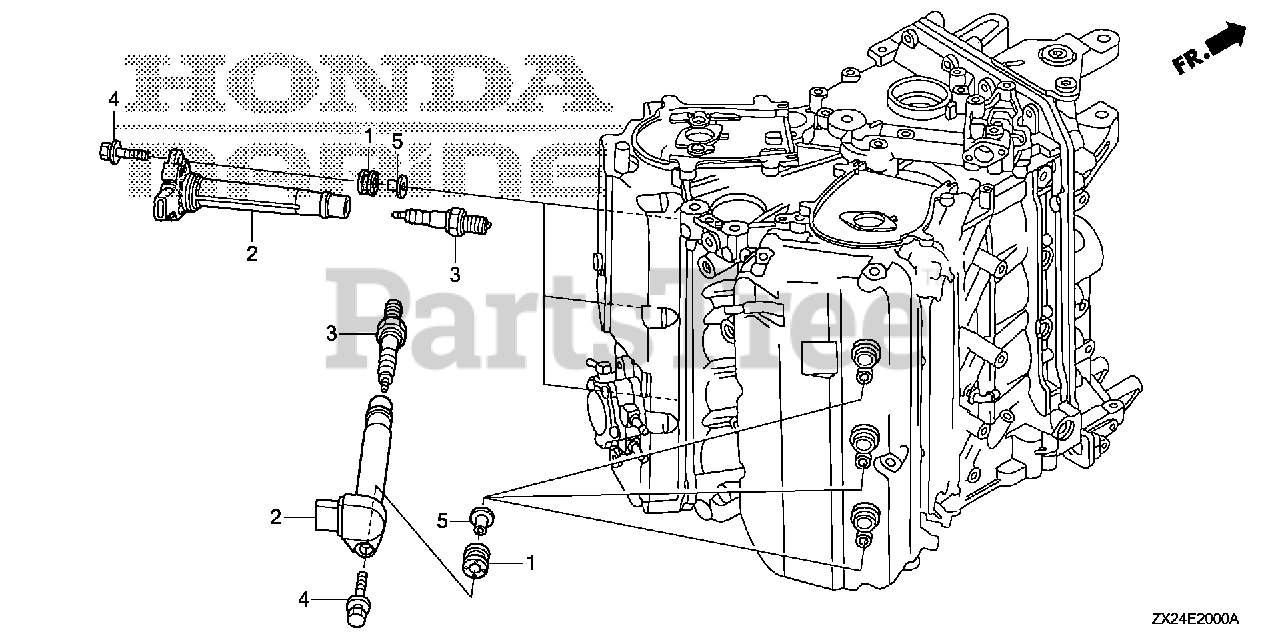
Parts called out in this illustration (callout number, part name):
1	GROMMET, ELECTRONIC PARTS CASE
2	COIL, PLUG HOLE
3	SPARK PLUG (ZFR6K-11E) (NGK)
3	SPARK PLUG (IZFR6K-11E) (NGK)
4	BOLT-WASHER (6X27)
5	COLLAR, MODULE IGNITION CONTROL CASE (CDI)
